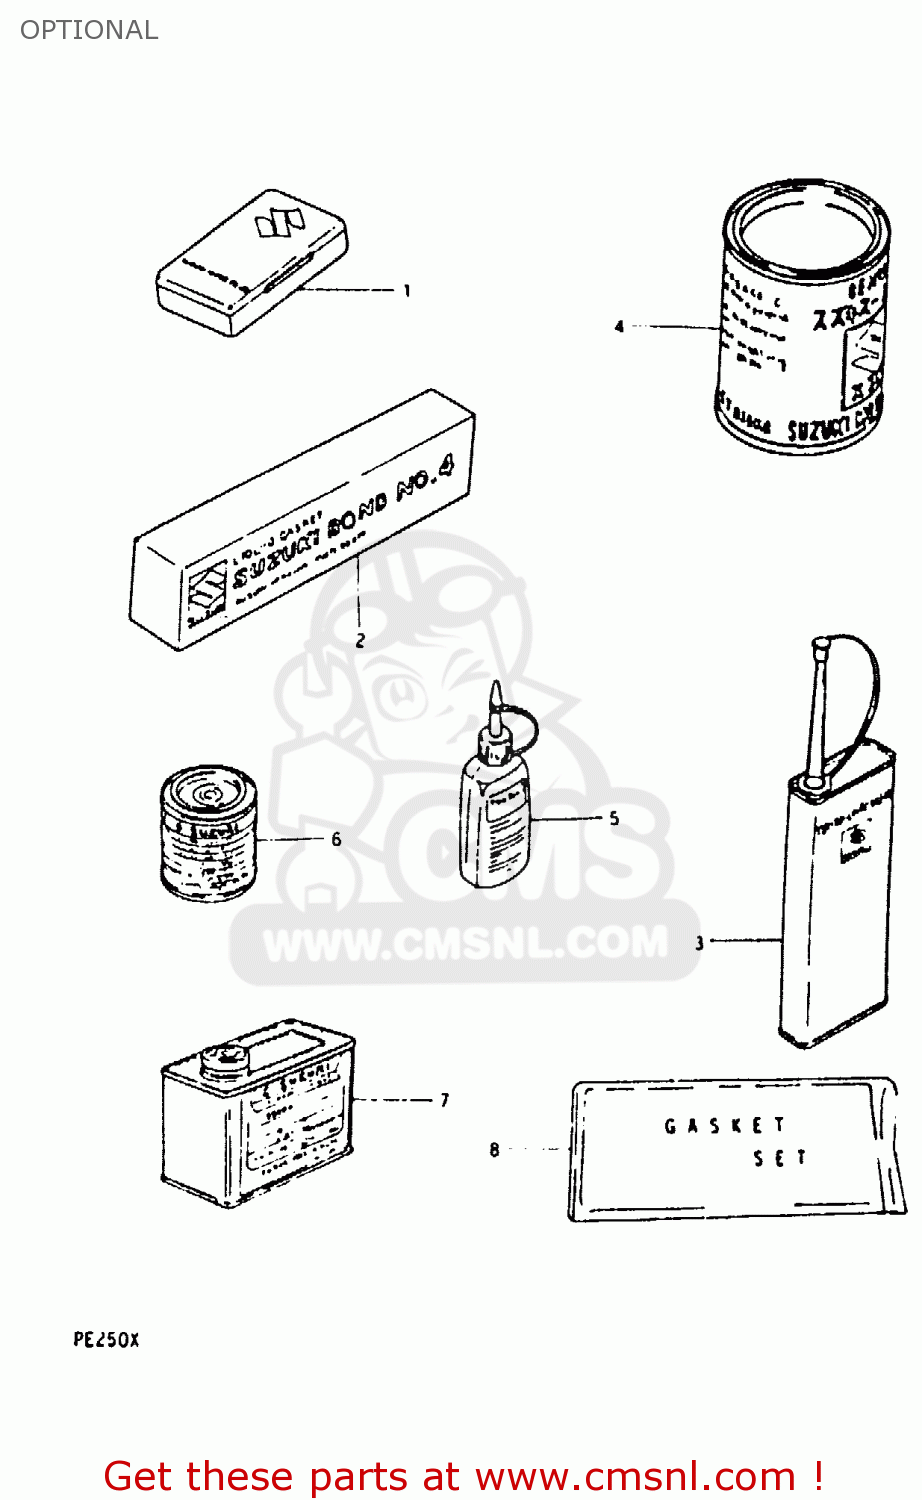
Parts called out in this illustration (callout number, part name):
1	TUBE REPARING TOOL
2	BOND 1104
3	THREAD LOCK NO.1401 CLEAR 200G
4	GREASE(C)EP2 LITHIUM 150G
5	THREAD LOCK NO.1342
6	PAINT,BLACK
7	PAINT (BLACK)
8	GASKET SET
